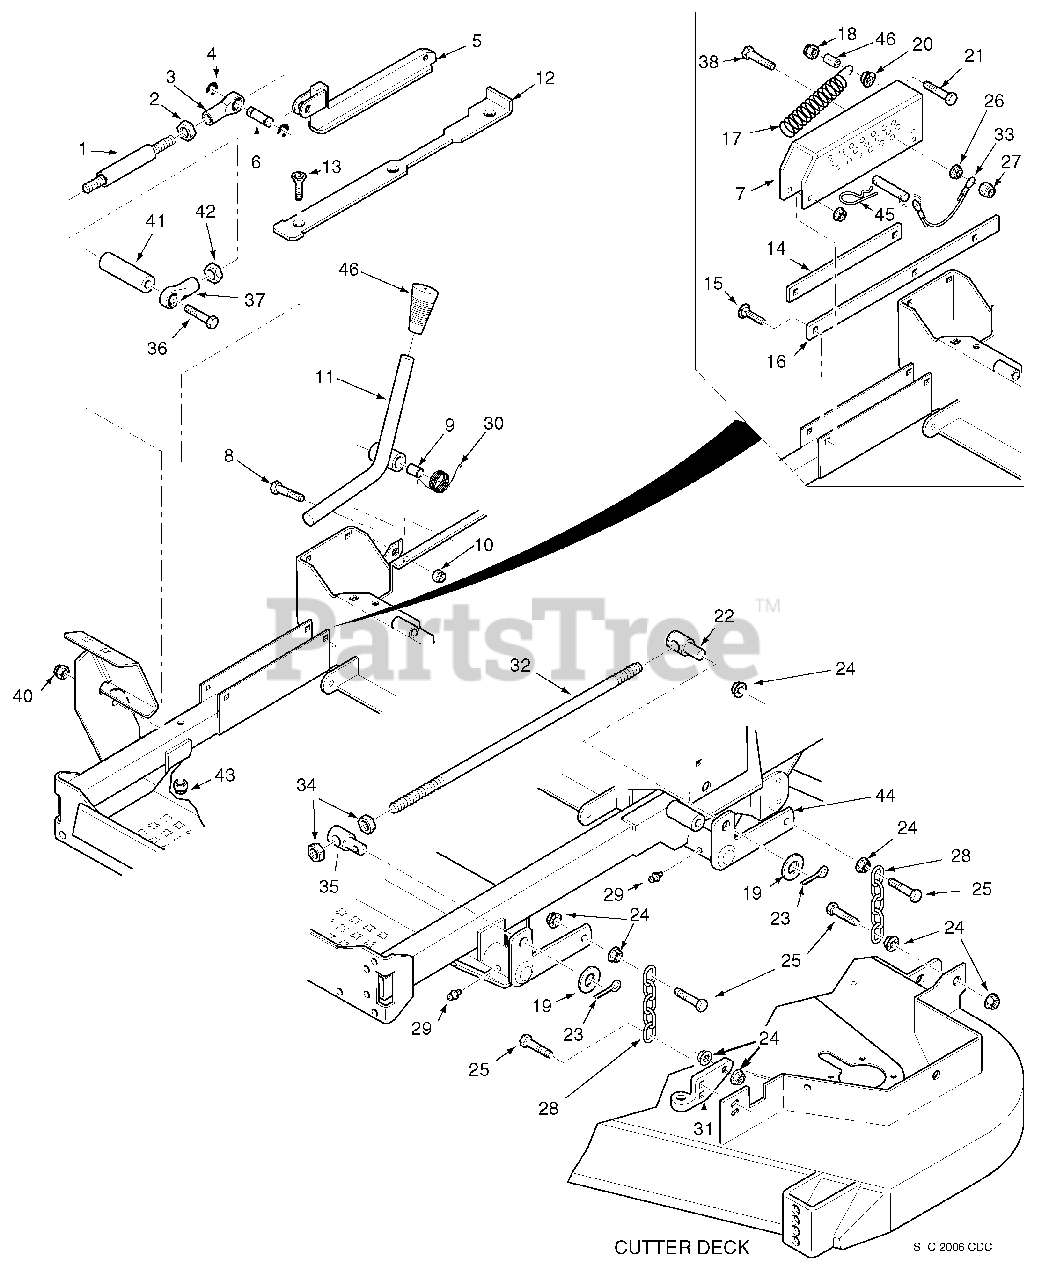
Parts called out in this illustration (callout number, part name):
1	Rod, Deck Lift Linkage
2	Nut, Jam 1/2-20 LH Thread
3	Rod End, 1/2-20 Female LH Thread
4	Retaining Ring, 1/2" Ext. "E"
5	Slide, Deck Height Adjust
6	Pin, Deck Lift
7	Bracket, Cutting Height Adjustment
8	Bolt, Hex Hd. 3/8-16 x 2-3/4"
9	Bushing .502" OD
10	Nut, Elastic Stop 3/8-16
11	Lever, Deck Latch
12	Slide, Cutting Height
13	Capscrew, 5/16-18 x 3" Flathead Hex Socket Grd. 8
14	Guide, Short
15	Bolt, Carriage 5/16-18 x 1"
16	Guide, Long
17	Spring, Helper
18	Nut, 3/8-16 Center Lock
19	Flatwasher, 5/8 (.656 x 1.312 x .095")
20	Nut, 3/8-16 Serr. Flng.
21	Bolt, Hex Hd. 3/8-16 x 1-1/4"
22	Swivel Joint LH
23	Cotter Pin, 3/16 x 1"
24	Nut, Serr. Flng. 3/8-16
25	Bolt, Hex Hd. 3/8-16 x 1-1/2"
26	Nut, Serr. Flng. 3/8-16
27	Nut, Elastic Stop 3/8-16
28	Chain
29	Grease Fitting, 1/4-28 Self Tap
30	Torsion Spring
31	Lever Assy., Deck Level
32	Stud, 1/2-13 x 20"
34	Nut, 5/8-11 UNC
35	Swivel Joint RH
36	Bolt, Hex Hd. 1/2-13 x 5"
37	Rod End, 1/2-20 Female RH Thread
38	Bolt, Hex Hd. 3/8-16 x 3-1/2"
39	Spacer
40	Locknut, 1/4-20
41	Spacer
42	Nut, 1/2-20 UNF-2B RH Thread
43	Nut, Elastic Stop 5/16-18
44	Lift Bellcrank Weldment, LH Rear
45	Hair Pin Cotter, .177" x 3-1/4"
46	Grip, Deck Latch Lever
